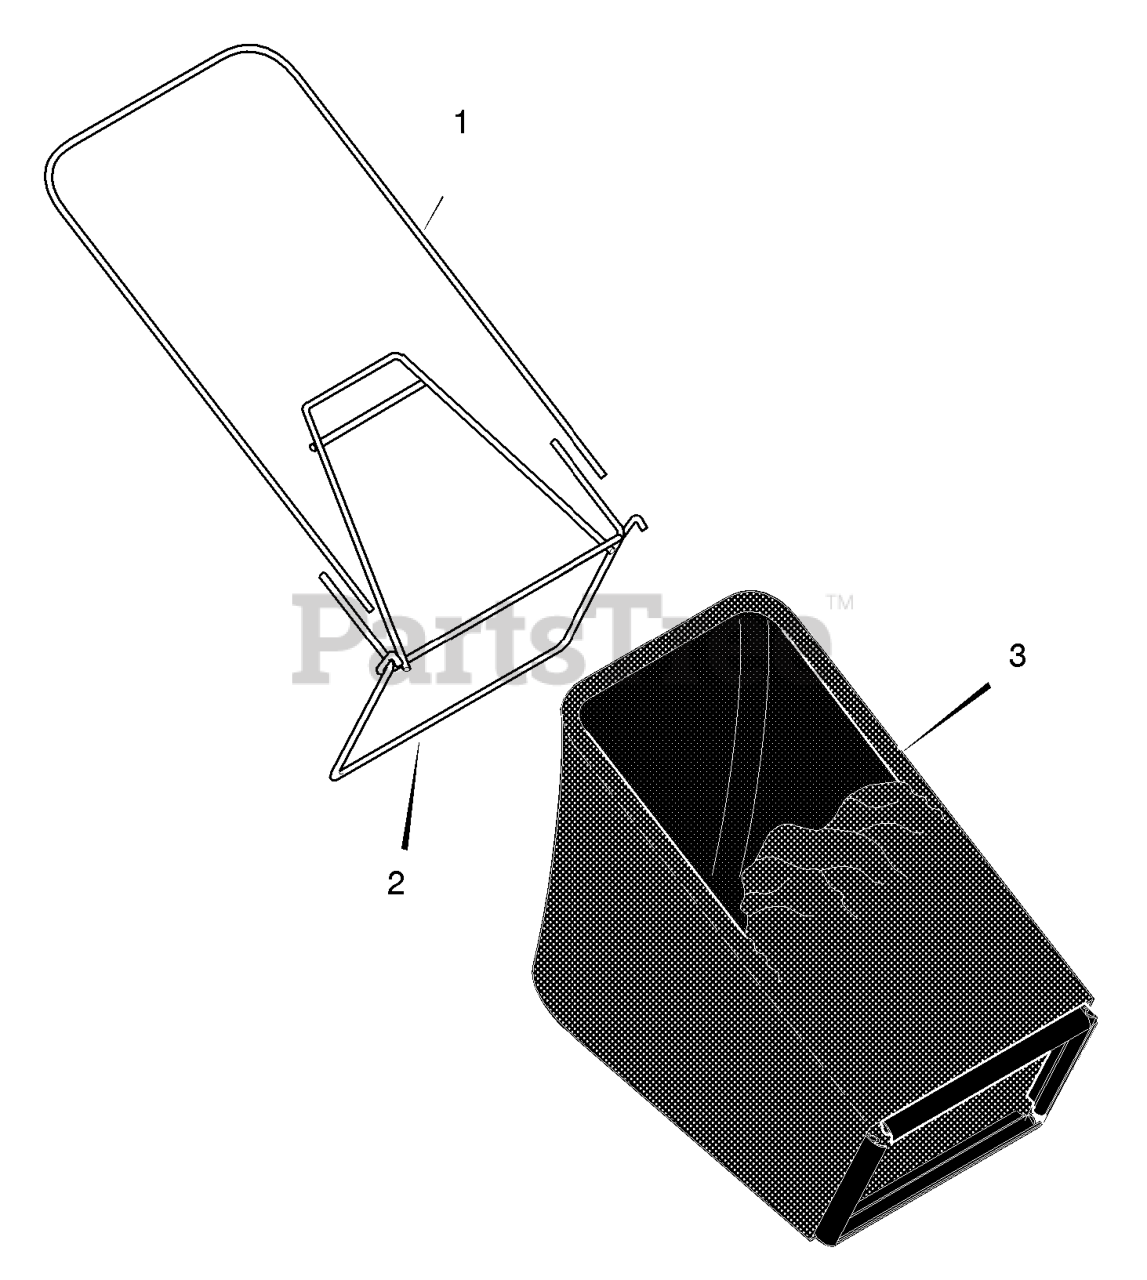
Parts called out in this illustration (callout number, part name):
1	Tube, Bag
2	Frame Assembly
3	Bag, Cloth - Black
